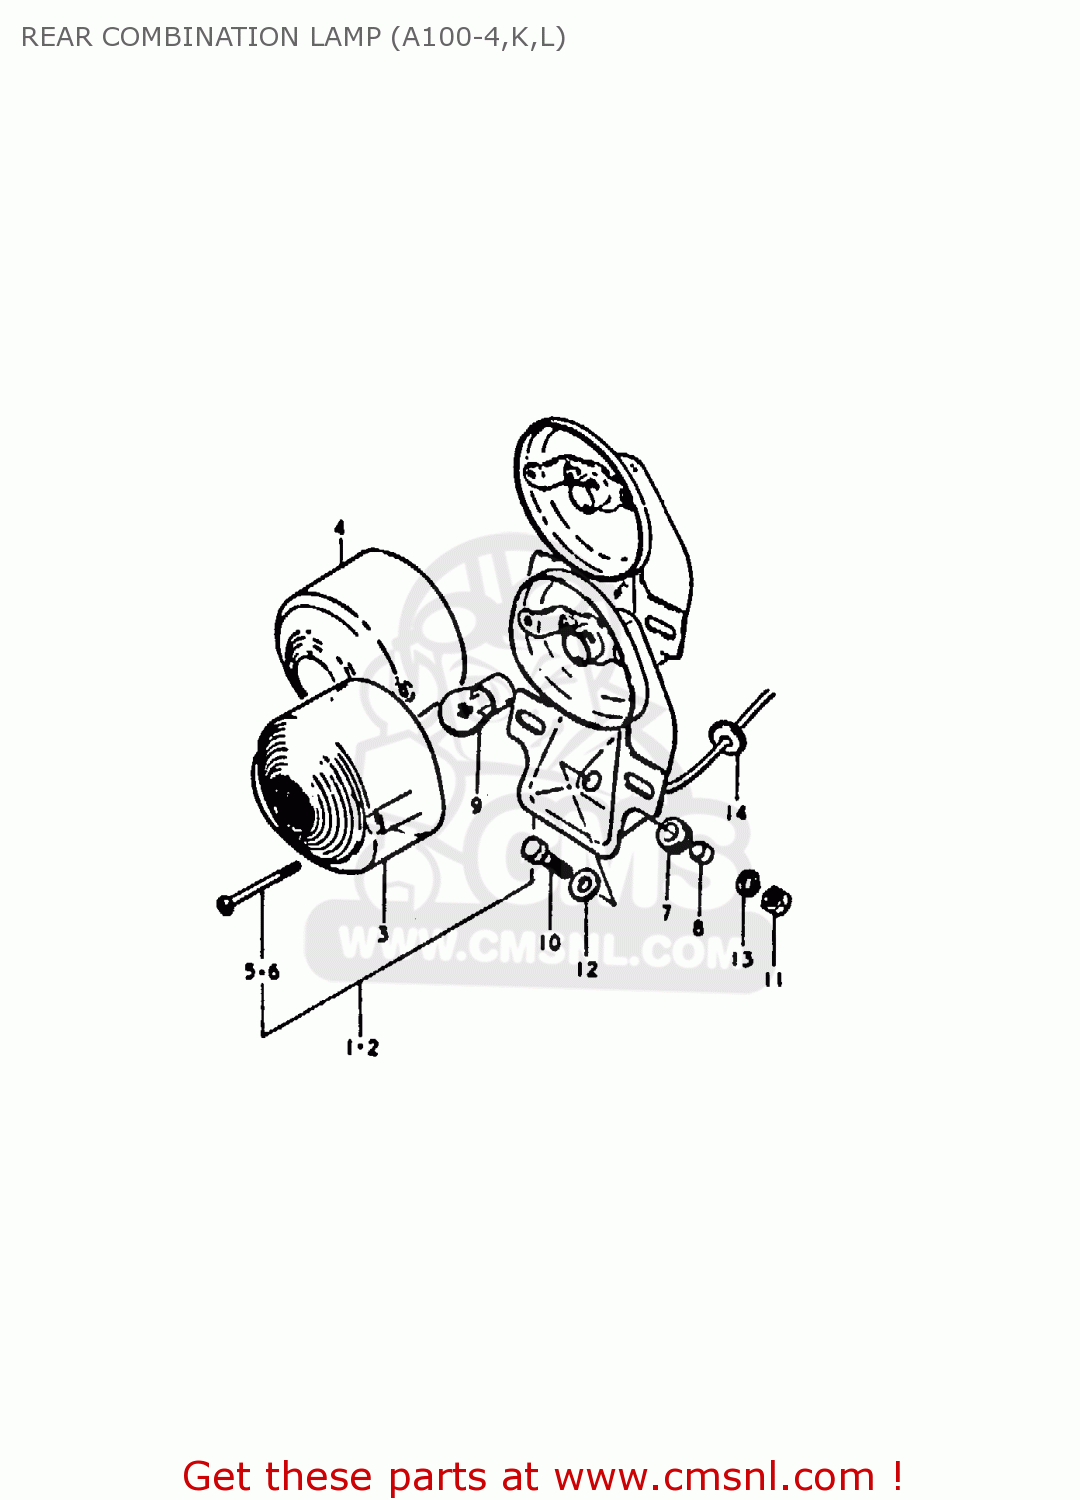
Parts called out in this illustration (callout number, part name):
7	CUSHION
8	SPACER,REAR COMBINATION LAMP
9	BULB(6V10/3W,STANLEY,A4854H)
10	BOLT
11	NUT
12	WASHER
13	LOCK WASHER
14	GROMMET
